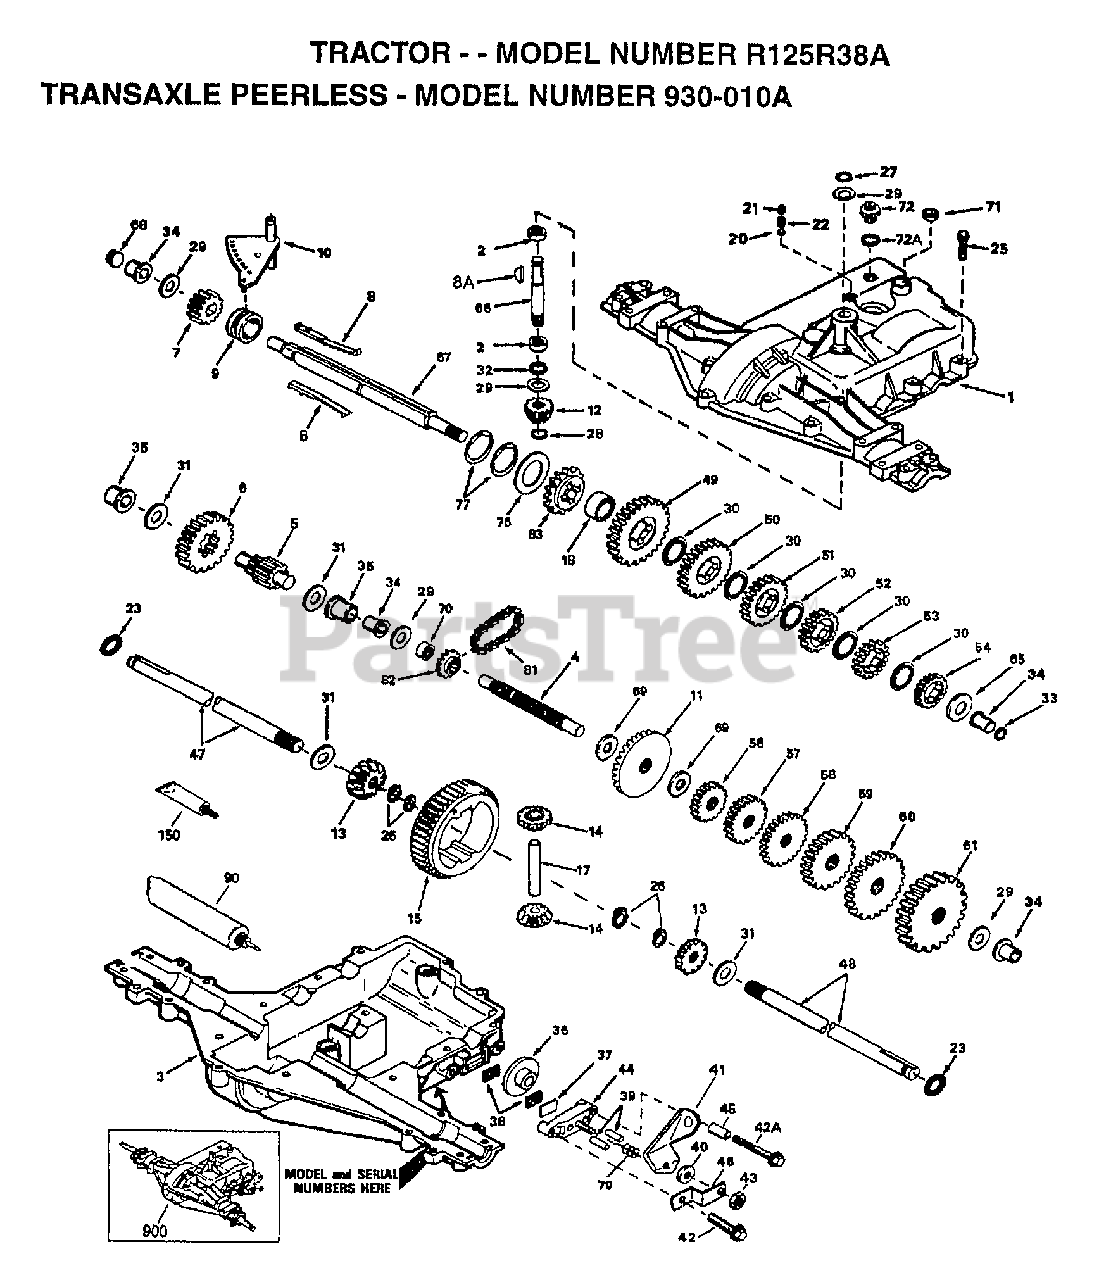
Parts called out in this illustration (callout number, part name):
1	TRANSAXLE COVER
2	BEARING, NEEDLE
3	TRANSAXLE CASE
4	SHAFT, COUNTER
5	OUTPUT SHAFT AND PINION
6	GEAR, OUTPUT
7	GEAR, SPUR, 15 TEETH
8A	KEY, WOODRUFF
9	COLLAR, SHIFTER
10	ROD & FORK ASSY, SHIFT
11	GEAR, BEVEL, 42 TEETH
12	BEVEL PINION, INPUT
13	GEAR, BEVEL
14	GEAR, BEVEL, PINION
18	SPACER, NEUTRAL
20	BALL STEEL, 5/16" DIA.
21	SCREW, 3/8-16 X 3/8"
25	SCREW, 1/4-20 X 1-1/4
26	RING RETAINER
27	RING, RETAINER
28	RETAINING RING
29	WASHER THRUST
30	WASHER THRUST
33	SEAL, SQUARE CUT
34	BUSHING, FLANGED
35	BUSHING, FLANGED
36	DISK, BRAKE
37	PLATE BRAKE PAD
41	BRAKE LEVER
42	SCREW, 1/4-20 X 1-1/4
42A	SCREW, 1/4-20 X 2-1/4
43	LOCKNUT 5/16-24
44	HOLDER BRAKE PAD
46	BRKT BRAKE LEVER
49	GEAR, SPUR, 37 TEETH
50	GEAR, SPUR, 35 TEETH
51	GEAR, SPUR, 30 TEETH
52	GEAR, SPUR, 25 TEETH
53	GEAR, SPUR, 22 TEETH
54	GEAR, SPUR, 19T
56	GEAR, SPUR, 12 TEETH
57	GEAR, SPUR, 15 TEETH
58	GEAR, SPUR, 20 TEETH
59	GEAR, SPUR, 25 TEETH
60	GEAR, SPUR, 30 TEETH
61	GEAR, SPUR, 31 TEETH
65	WASHER, THRUST
66	SHAFT, INPUT
67	SHAFT, BRAKE, 4 KEYED
69	WASHER THRUST
71	SEAL SQUARE CUT
72	THREADED PLUG 9/16-18
76	WASHER, THRUST
77	INVERTED RETAINING RING
81	CHAIN, ROLLER
82	SPROCKET 9T
83	SPROCKET 18T (REV)
90	GREASE BENTONITE, 32 OZ.
150	GASKET ELIMINATOR
900	REPLACEMENT TRANSAXLE
